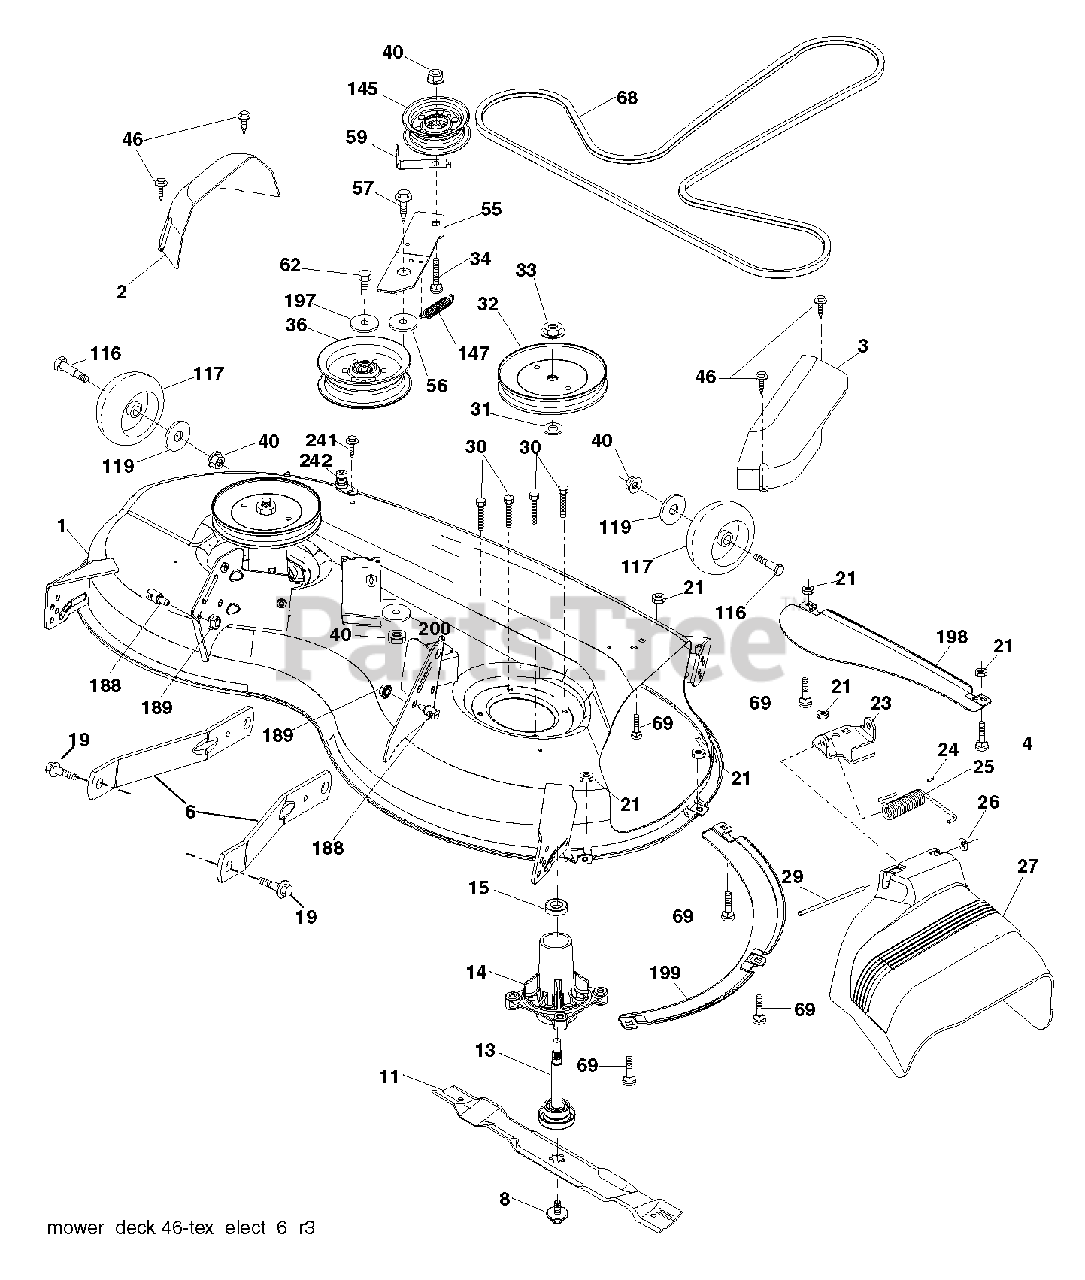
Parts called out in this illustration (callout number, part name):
2	COVER.MANDREL.LH.46"
3	COVER MANDREL RH
6	ARM.SUSPENSION.MOWER.R
8	BOLT.WASHER.ASM.7/16-2
11	BLADE 46" HI LIFT
13	SHAFT.ASM.MDRL.N/GREASE.38
14	HOUSING MANDREL
15	BEARING
19	BOLT.SHOULDER
23	BRKT.DEFLECTOR.38"2005+
24	CAP-SLEEVE LT
25	SPRING.TORSION.DEFLECT
26	NUT PUSH M
27	SHIELD.DEFLECTOR.MOWER.46"BLAC
29	ROD.HINGE
30	SCREW, WASHER HEAD
31	WASHER.SPACER.MANDREL
33	NUT.FLANGE.LOCK.TOP
34	BOLT.3/8-16X1.50
46	SCREW.1/4-20X5/8
55	IDLER.ARM
56	SPACER.RETAINER
57	SCREW 3/8-16X1
59	GUARD, BELT
62	BOLT-HEX EAK
68	V BELT
69	BOLT
117	WHEEL.GAGE.HALF.SPOKED
147	SPRING.MOWER.DRIVE.ELECTRIC
188	STUD.FASTNER.W/ANTI-ROTATE
189	NUT LOCK HEX FLANGE 5/16-18
198	BAFFLE CENTER FRONT
199	BAFFLE FRONT RH
200	WASHER.13/32 X 1 X 1/2.11GUARD
242	PORT.WASHOUT
